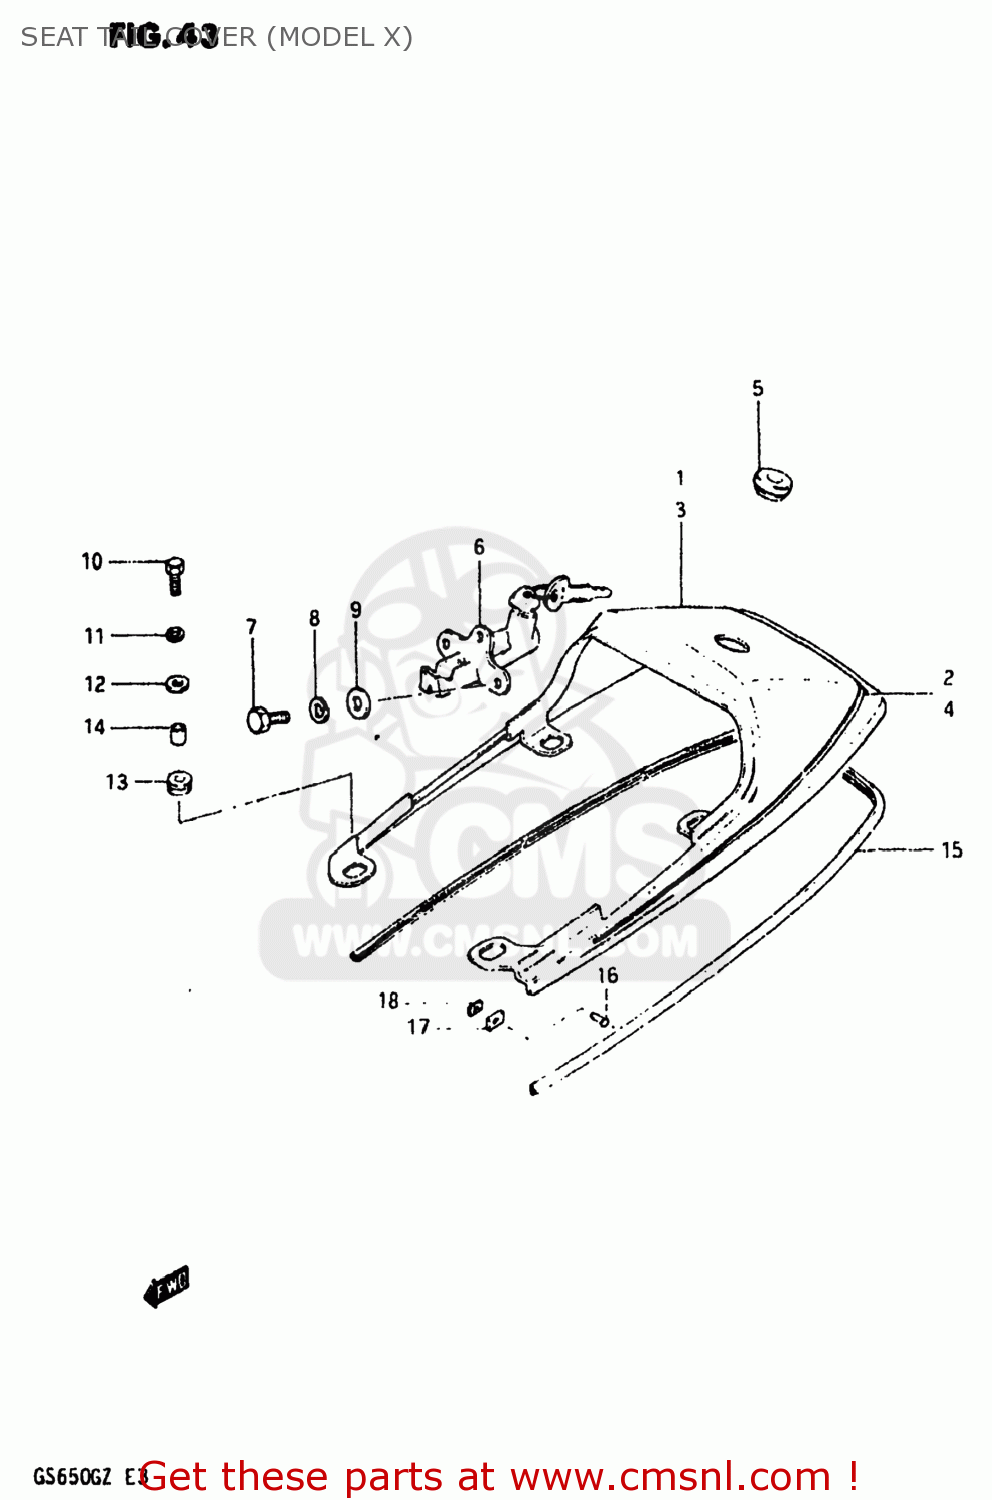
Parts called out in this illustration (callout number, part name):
1	COVER ASSEMBLY,SEAT TAIL
2	TAPE SET,BOX SEAT TAIL
3	COVER ASSEMBLY,SEAT TAIL
4	TAPE SET,BOX SEAT TAIL
5	GROMMET,SEAT LOCK HOLE
6	LOCK SET,SEAT
7	BOLT
8	LOCK WASHER
9	WASHER
10	BOLT
11	LOCK WASHER
12	WASHER(6,5X22X1.6)
13	CUSHION
14	SPACER(6.5X10.5X12)
15	MOLDING,SEAT TAIL COVER
16	RIVET
17	CUSHION,SEAT TAIL
18	NUT
